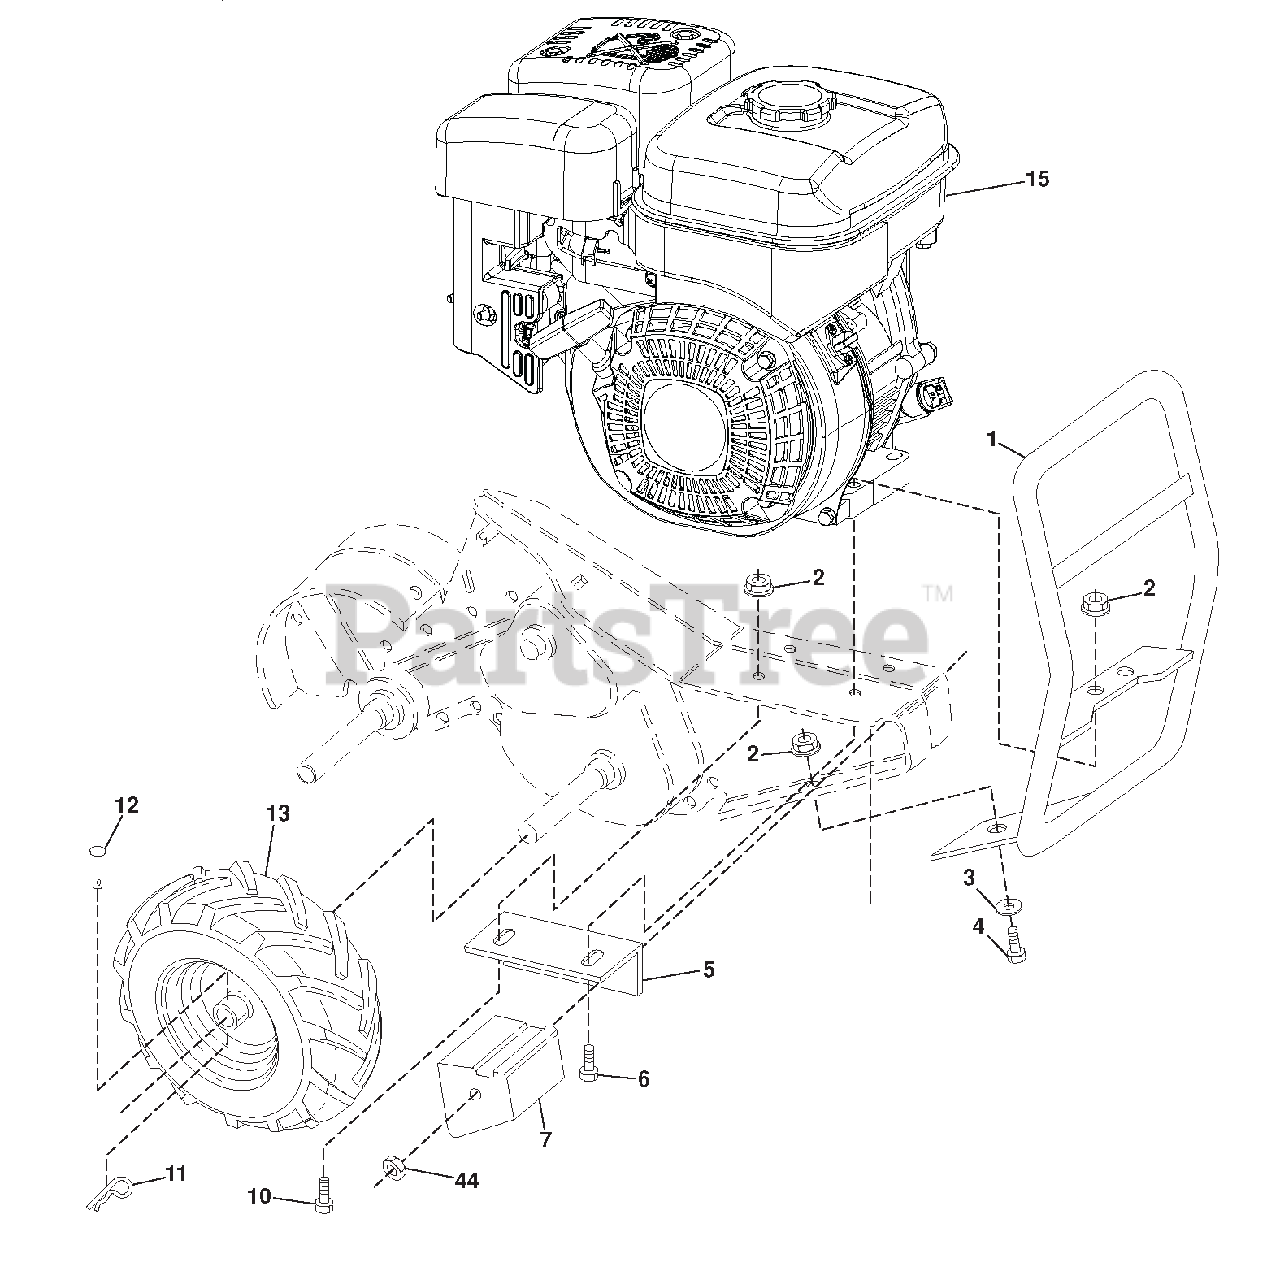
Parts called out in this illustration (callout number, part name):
2	Nut, Hex, Flangelock
3	Washer 11/32 x 11/16 x 16 Ga.
4	Bolt, Hex Head 5/16-18 x 3/4
5	Bracket, Reinforcement
6	Bolt, Fin Hex 5/16-18 unc x 1-
7	Counter Weight, RH
10	Bolt, Hex Head, Gr. 25/16-18 x
11	RETAINER SPRING
12	Rivet, Drilled
15	ENGINE
44	Nut Keps Hex 3/8-16 unc
